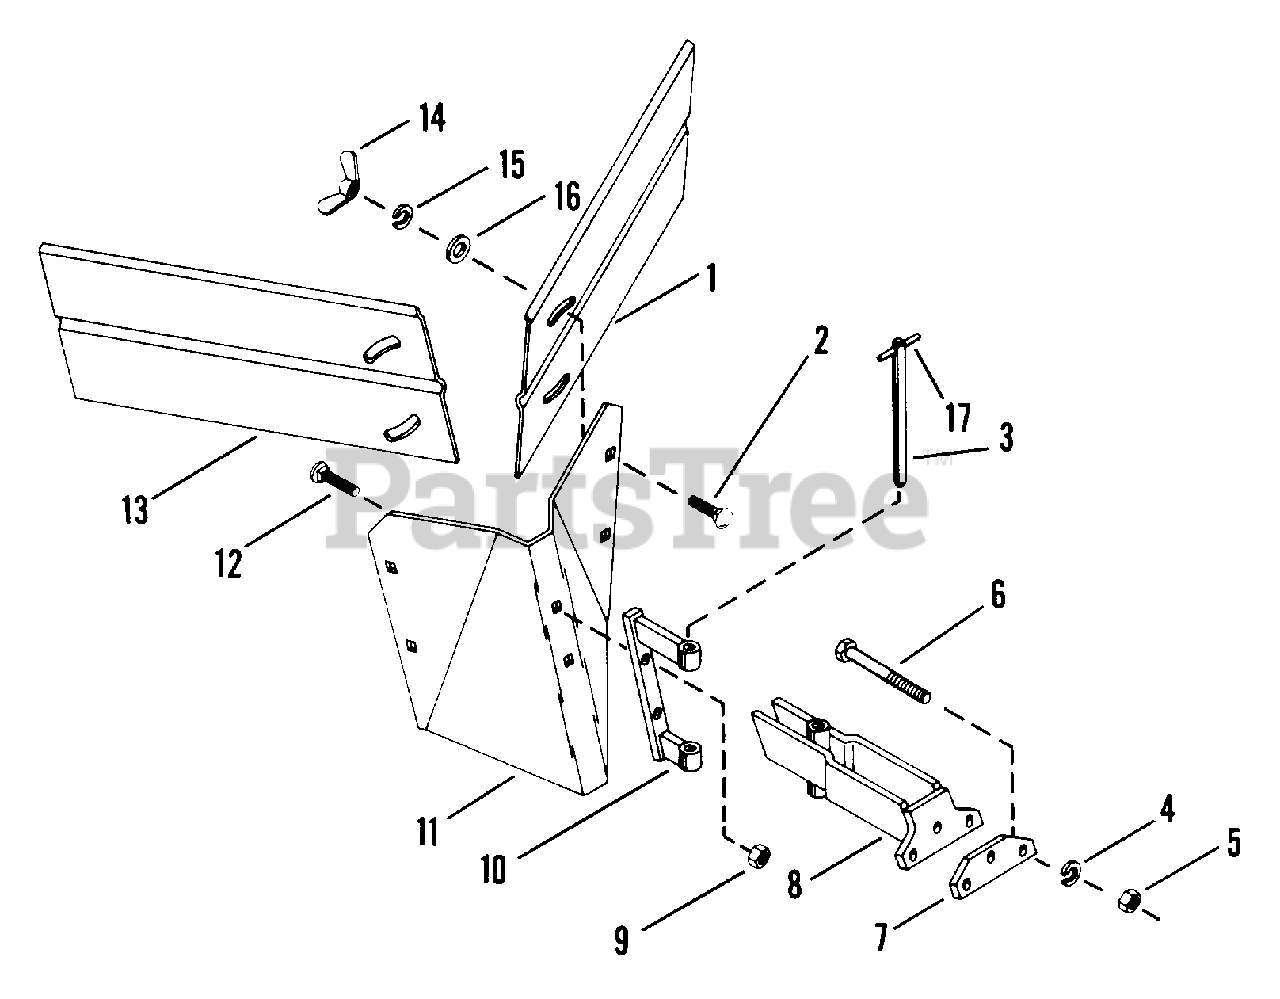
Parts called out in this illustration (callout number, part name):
1	WING, LEFT
2	BLT-RDHDSQNK .31-18X1.25 SHTPL
3	PIN ASSEMBLY
4	WSHR-LK .375X.115 HVY PL
5	NUT-JAM .375-16 PL
6	BLT-HEX .38-16X3.50 PL GR5
7	PLATE
8	MOUNT WELDMENT
9	NUT-LK TOP .375-16 GR C YWZC
10	TIP MOUNT WELDMENT
11	CHISEL TIP
12	BLT-RDHDSQNK .38-16X1.25 GR5PL
13	WING, RIGHT
14	NUT-WING .312-18 YWZC
15	WSHR-LK .313X.093 MED HICLR
16	WSHR-FL-STL .328X1.0X.094
17	PIN-ROLL .250X3.00
